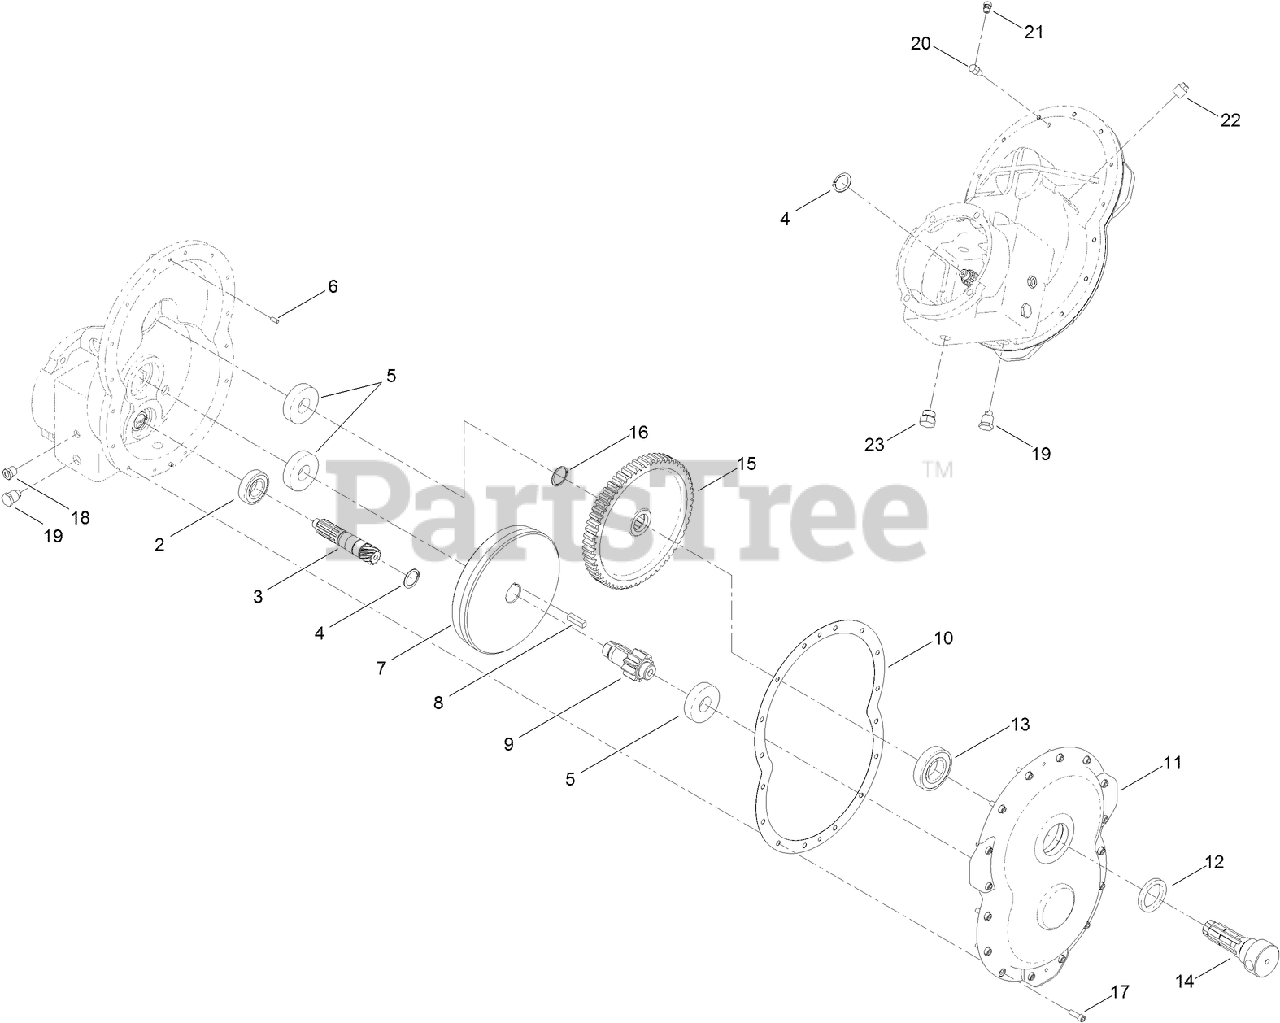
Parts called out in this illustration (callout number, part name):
2	BEARING-BALL
3	SHAFT-INPUT, PINION
4	RING-EXTERNAL
5	BEARING-ROLLER
7	GEAR-HELICAL
8	KEY-SQUARE
9	PINION
10	GASKET-GEARCASE
11	COVER-GEARCASE
12	SEAL-SHAFT
13	BEARING-BALL
14	SHAFT-OUTPUT, GEARCASE
15	GEAR-SPUR
16	RING-SNAP, EXTERNAL
17	SCREW-HSH
18	PLUG-SIGHT, OIL
19	PLUG-HH, MAGNETIC
20	ELBOW-CONNECTION
21	BREATHER-ALEMITE
